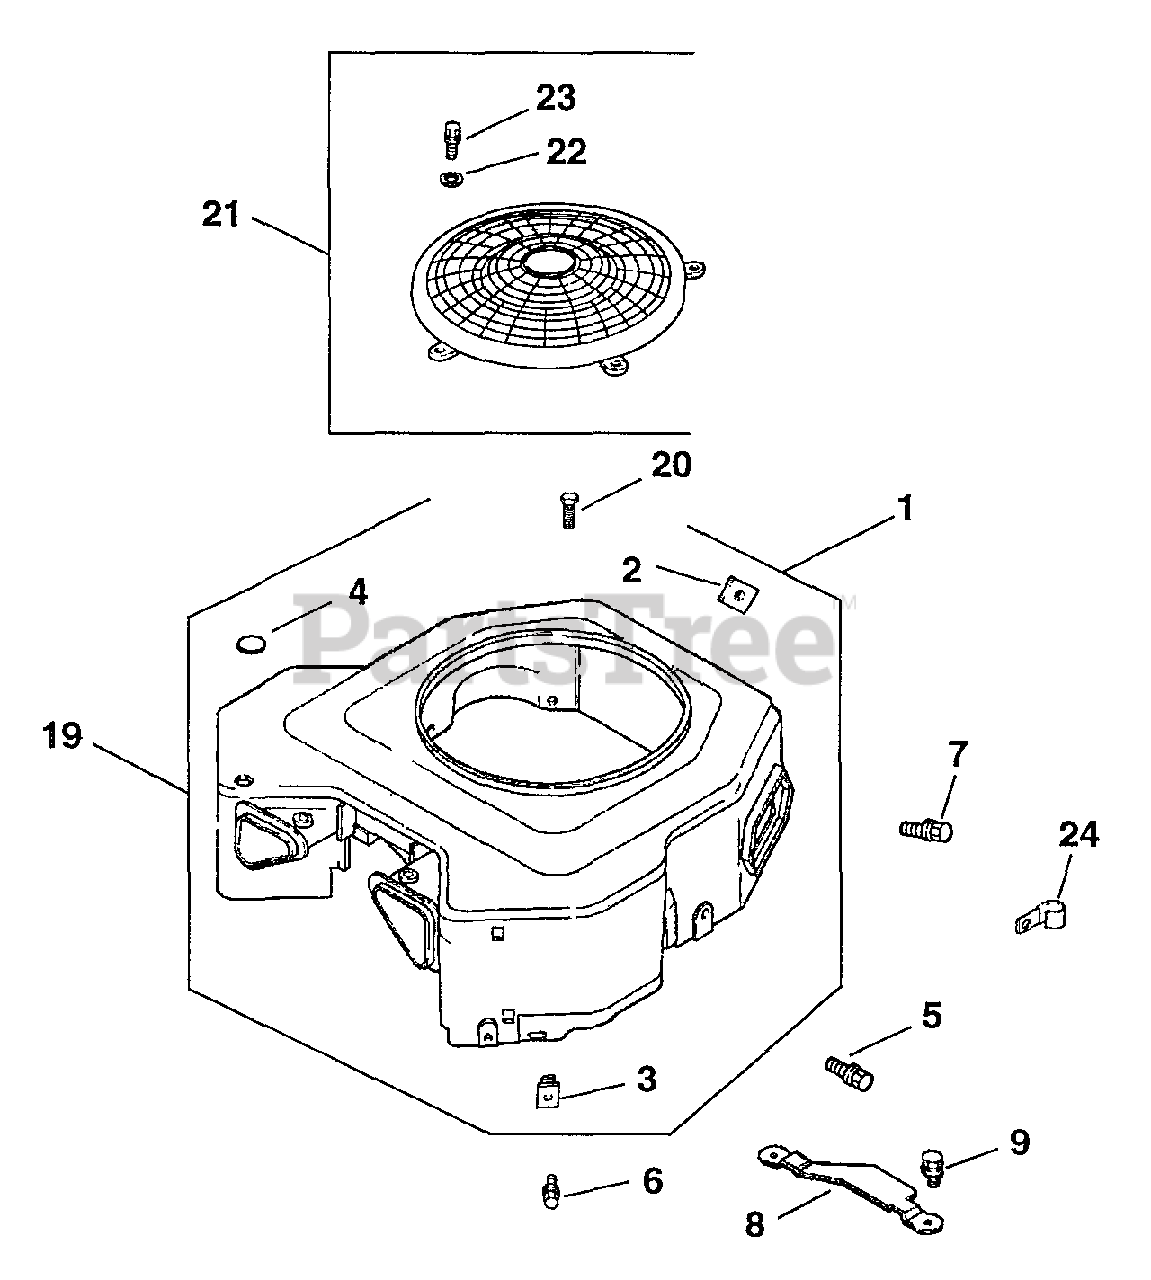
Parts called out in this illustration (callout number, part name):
2	NUT, PLASTIC (KM)-USE 25 100 37-S
3	NUT, PLASTIC
4	PLUG, BUTTON 9/16
5	SCREW - USE M-545016
6	Screw, hex. flange M5x0.8x20
7	Screw, hex. flange M5x0.8x16
8	BRACKET - USE 24 126 71
9	SCREW - USE M-645016
19	HOUSING - USE 24 027 83
21	KIT, FIXED GUARD
22	WASHER, FLAT 7/32"
23	SCREW, LBD SCKT PAN M5X0.8X10
